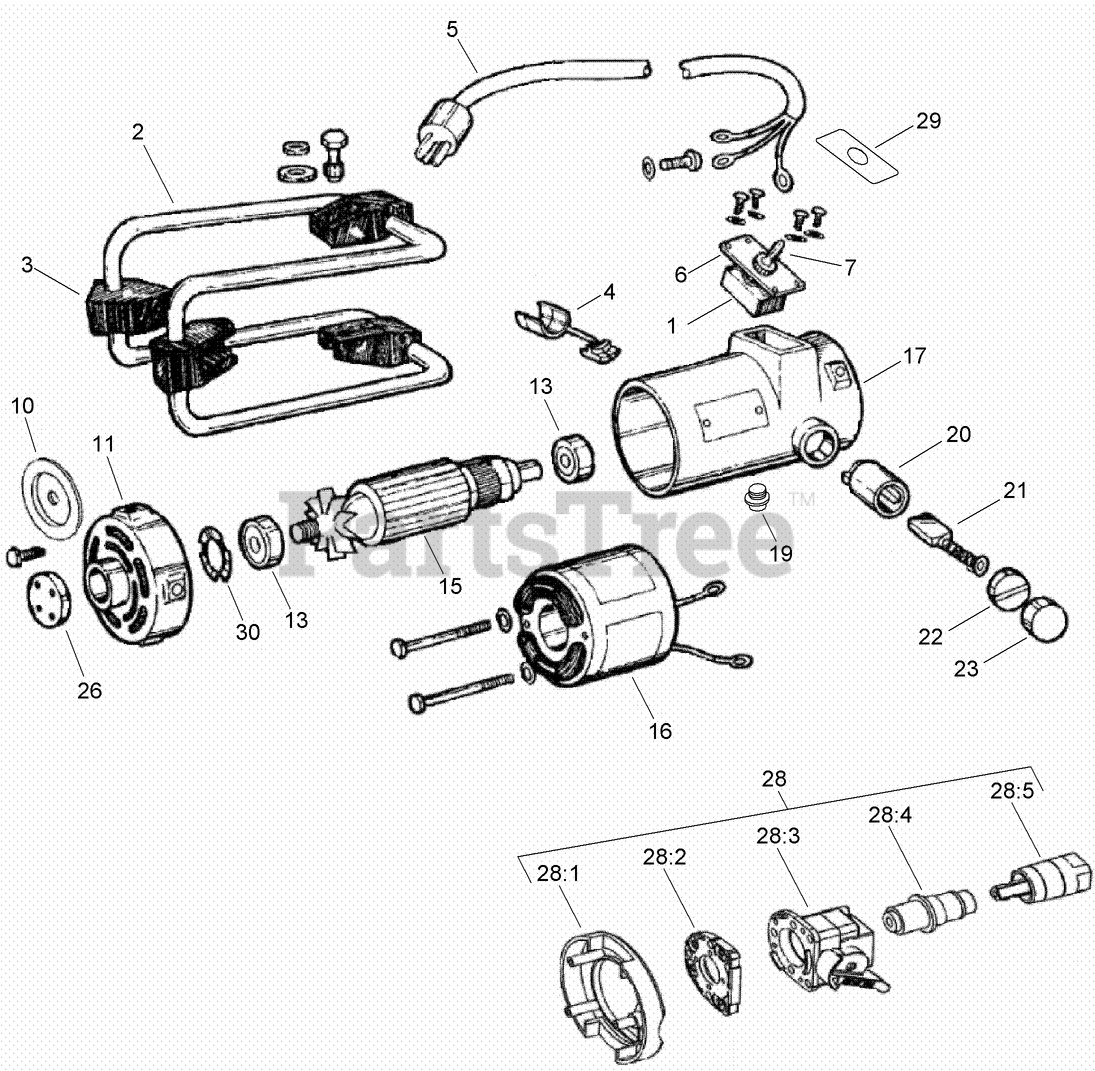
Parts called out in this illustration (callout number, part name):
1	KILL SWITCH ASM
2	FRAME ASM
3	MOUNT-SHOCK
4	STRAIN RELIEF ASM
5	CORD ASM
6	SWITCH PLATE ASM
7	BOOT-RUBBER, SWITCH
10	BAFFLE ASM
11	BELL-END
13	BEARING
15	ARMATURE (115V)
16	FIELD (115V)
17	HOUSING
19	PLUG-PORT, ACCESS
20	HOLDER-BRUSH
22	CAPSCREW
23	PROTECTIVE CAP, THREADED
28	QUICK DISCONNECT KIT
28:1	BAFFLE-RH
28:2	SPACER
28:3	CASING-ADAPTOR
28:4	CORE ADAPTOR ASM
28:5	COUPLER-SHAFT
29	DECAL-SWITCH PLATE
30	RING-TOLERANCE
